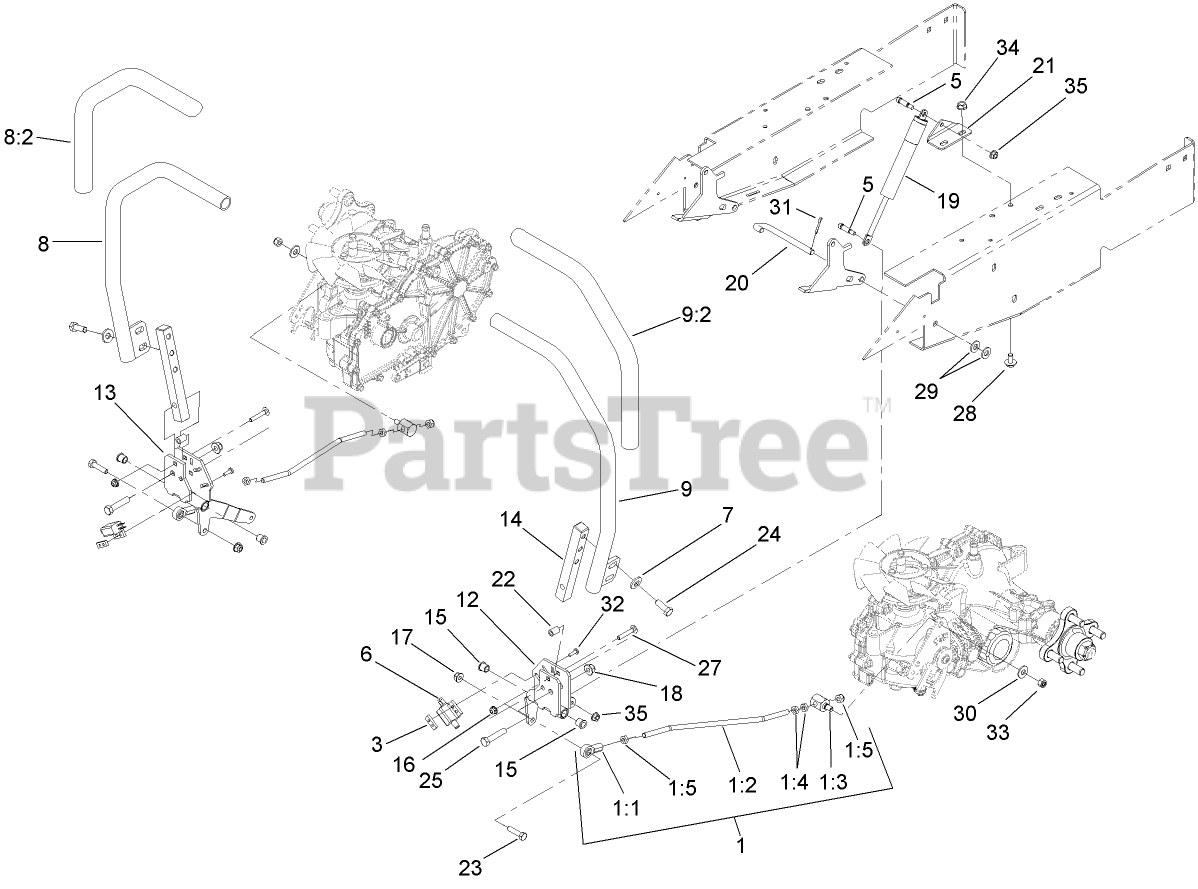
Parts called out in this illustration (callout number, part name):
1	STEERING ROD ASM
1:1	BALLJOINT-RH
1:2	ROD-STEERING, LH
1:3	TRUNNION
1:4	NUT-JAM
1:5	NUT-LOCK
3	PLATE-TAPPED
5	SCREW-HSH
6	SWITCH-POLE, SINGLE
7	WASHER-BELLEVILLE
8	RH CONTROL LEVER ASM
8:2	GRIP-FOAM
9	LH CONTROL LEVER ASM
9:2	GRIP-FOAM
12	CONTROL-STEERING, RH
13	CONTROL-STEERING, LH
14	MOUNT-POST, LEVER
15	BEARING
16	NUT-HF
17	NUT-HF, NI
18	NUT-HF, NI
19	DAMPER-CONTROL, MOTION
20	SHAFT-PIVOT, CONTROL
21	BRACKET-DAMPER
22	SPACER
23	SCREW-HH
24	SCREW-HH
25	SCREW-HH
27	SCREW-CARR
28	SCREW-HHF
29	WASHER-FLAT
30	WASHER-FLAT
31	PIN-COTTER
32	SCREW-PPH
33	NUT-LOCK
34	NUT-HF
35	NUT-HF
